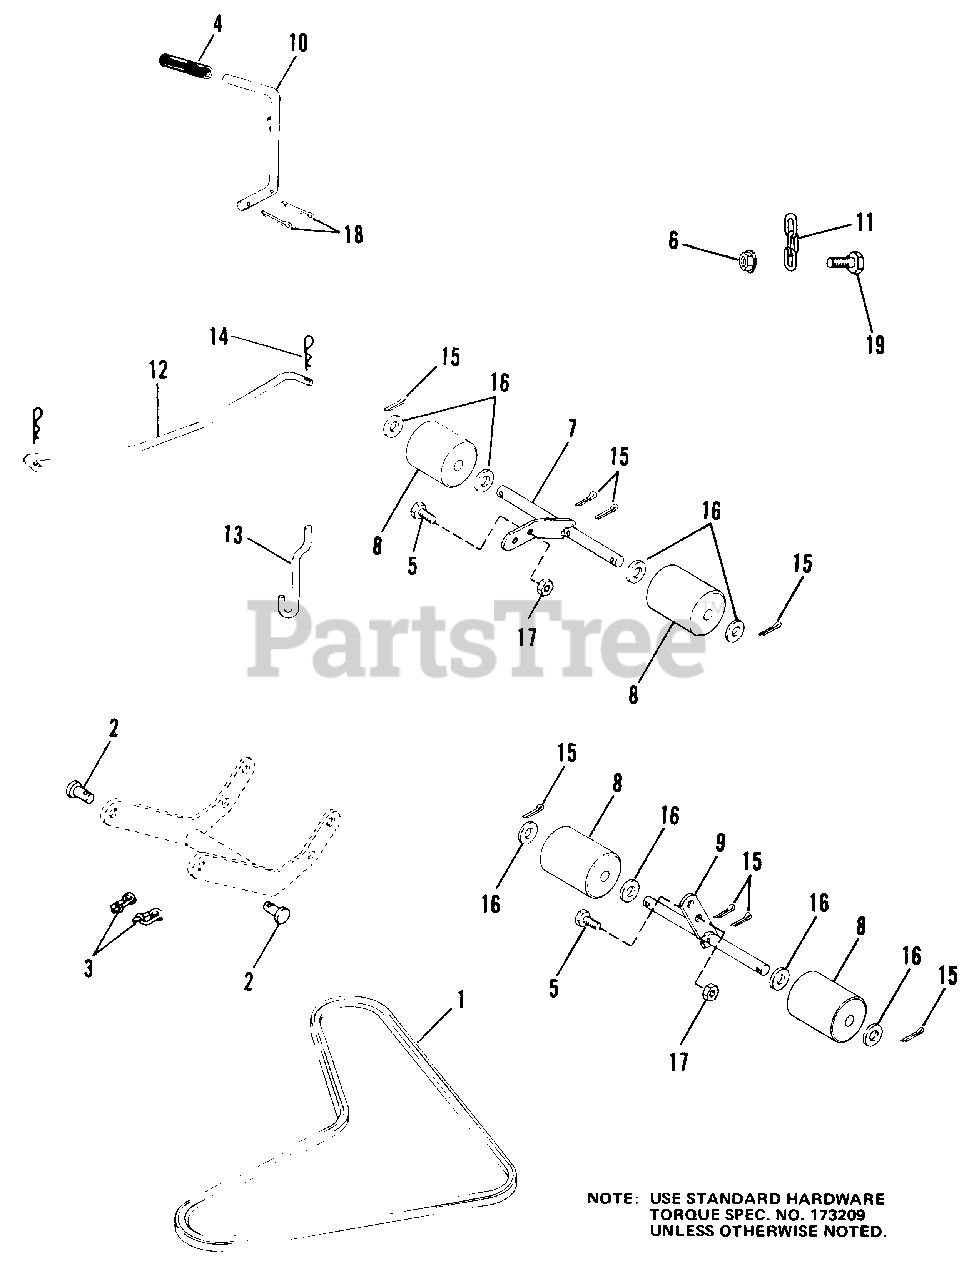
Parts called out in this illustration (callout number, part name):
1	V-BELT
3	CLIP, Safety Pin
4	HANDLE, Grip
5	CAPSCREW, Hex Hd., 3/8-16 x 1
6	NUT, Flange, 3/8-16
7	SHAFT ASSY, R.H. Roller
9	SHAFT ASSY, L.H. Roller
10	ROD, Control
11	CHAIN, Lift
14	CLIP, Spring (Serviced in 5 pk)
15	PIN, Cotter, 1/8 x 1
16	WASHER, Plain, 5/16
17	LOCKNUT, Hex, 3/8-16
18	PIN, Cotter, 3/32 x 1
19	CAPSCREW, Hex Hd., 5/16-18 x 1
